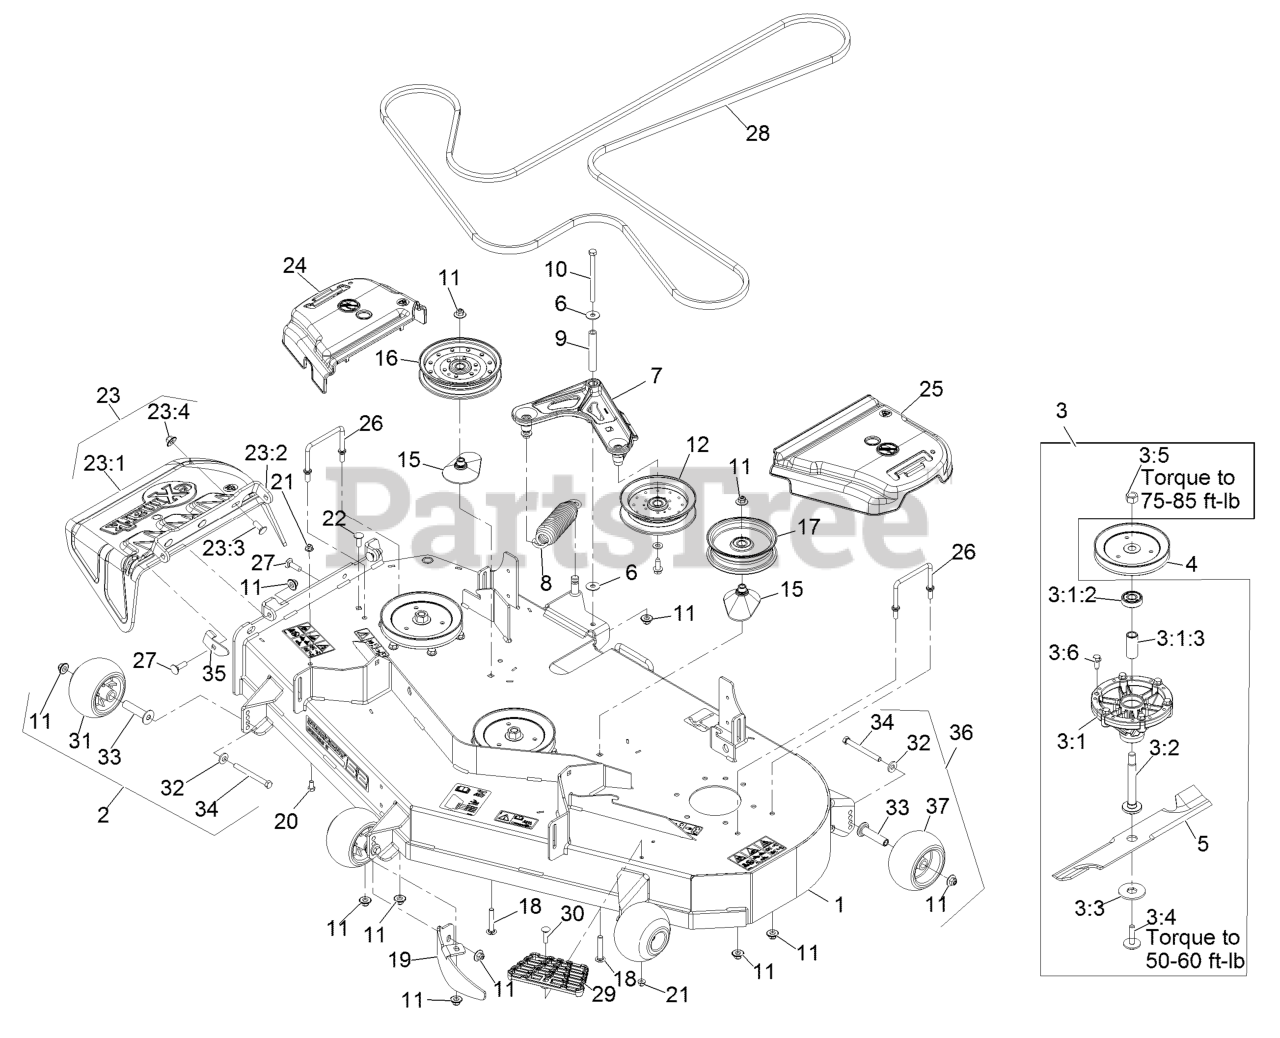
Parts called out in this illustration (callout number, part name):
1	ASM-Deck W/Decals 523
2	Kit, Anti-Scalp Roller
3	ASM, Cutter Housing Complete
3:1	ASM-Cutter Housing
3:1:2	Bearing
3:1:3	Spacer-Bearing
3:2	Spindle-Hex Pilot
3:3	Washer-Hex Blade Drive
3:4	Bolt-Blade, Sem
3:5	Nut-Hex 5/8-18
3:6	Screw-Thread Forming
4	Sheave,Blade Drive 6.50
5	Blade, Low Lift
5	Blade, Solid
5	Blade, Mulching
5	Blade-Notched
5	Blade-Extreme 2, 18.00"
7	ASM-Idler Arm W/Bearings
8	Spring-Extension
9	Bushing
10	Screw-HH 3/8-16 X 4 3/4
11	Nut-Nyloc 3/8-16 Flg
12	Idler-Pulley, Flanged
15	Spacer-Pulley
16	Pulley-Idler, Flat
17	Pulley-Idler Flat
18	Bolt-Carriage 3/8-16 X 2 1/4
19	Baffle-Dogleg, Lze-Pns-52
20	Screw-HH 5/16-18 X 5/8
21	Nut-Nyloc 5/16-18 Flg
22	Bolt-Carriage 3/8-16 X 1
23	ASM,Discharge Chute
23:1	Chute, Discharge
23:2	Bracket,Discharge Chute
23:3	Bolt-Carriage 3/8-16 X 1
23:4	Nut-Nyloc 3/8-16 Flg
24	Cover-Belt, RH
25	Cover-Belt, LH
26	Wireform-Cover
27	Bolt-Carriage 3/8-16 X 1 1/4
28	Belt-V
29	Step-Deck
30	Bolt-Carriage 5/16-18 X 1 1/4
31	Roller-Anti-Scalp
32	Washer-Spring Disc 3/8
33	Axle, Roller
34	Screw-HH 3/8-16 X 3 3/4 Gr 8
35	Stop-Discharge Chute
36	Kit-Antiscalp Roller
37	Roller-Scalp, Anti
